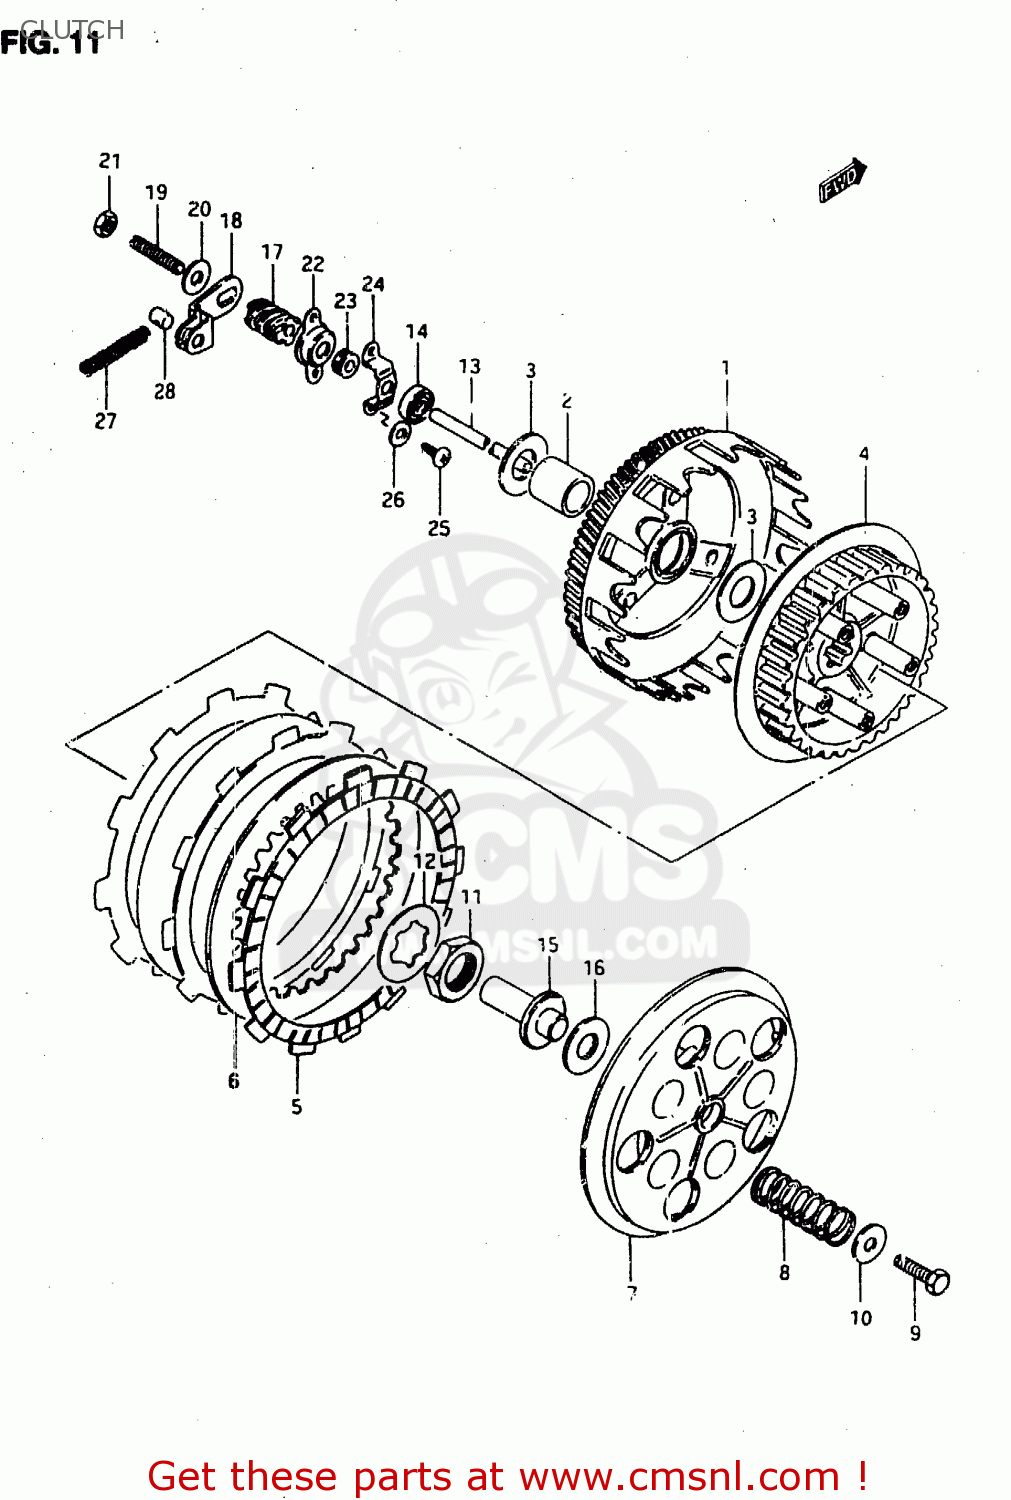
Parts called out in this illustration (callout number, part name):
1	GEAR ASSY,PRI DRIVEN(NT:17/73)
2	SPACER(17X22X28.5)
3	WASHER
4	HUB,CLUTCH SLEEVE
5	PLATE,CLUTCH DRIVE (NAS)
6	PLATE,CLUTCH DRIVEN (NAS)
7	DISC,CLUTCH PRESSURE
8	SPRING
9	BOLT(5X16)
10	WASHER (5.5X18X1)
11	NUT
12	WASHER,LOCK
13	ROD,CLUTCH PUSH
14	SEAL,OIL(5.5X16X8)
15	PIECE,CLUTCH PUSH
16	BEARING(10X22X2.8)
17	SCREW,CLUTCH RELEASE
18	ARM,CLUTCH RELEASE
19	SCREW(6X25)
20	WASHER
21	NUT
22	COVER,CLUTCH RELEASE SCREW
23	SEAL,DUST(5.3X13X5)
24	HOLDER,DUST SEAL
25	TAPPING SCREW
26	WASHER
27	SPRING
28	HOOK,CLUTCH RELEASE SCREW ARM
